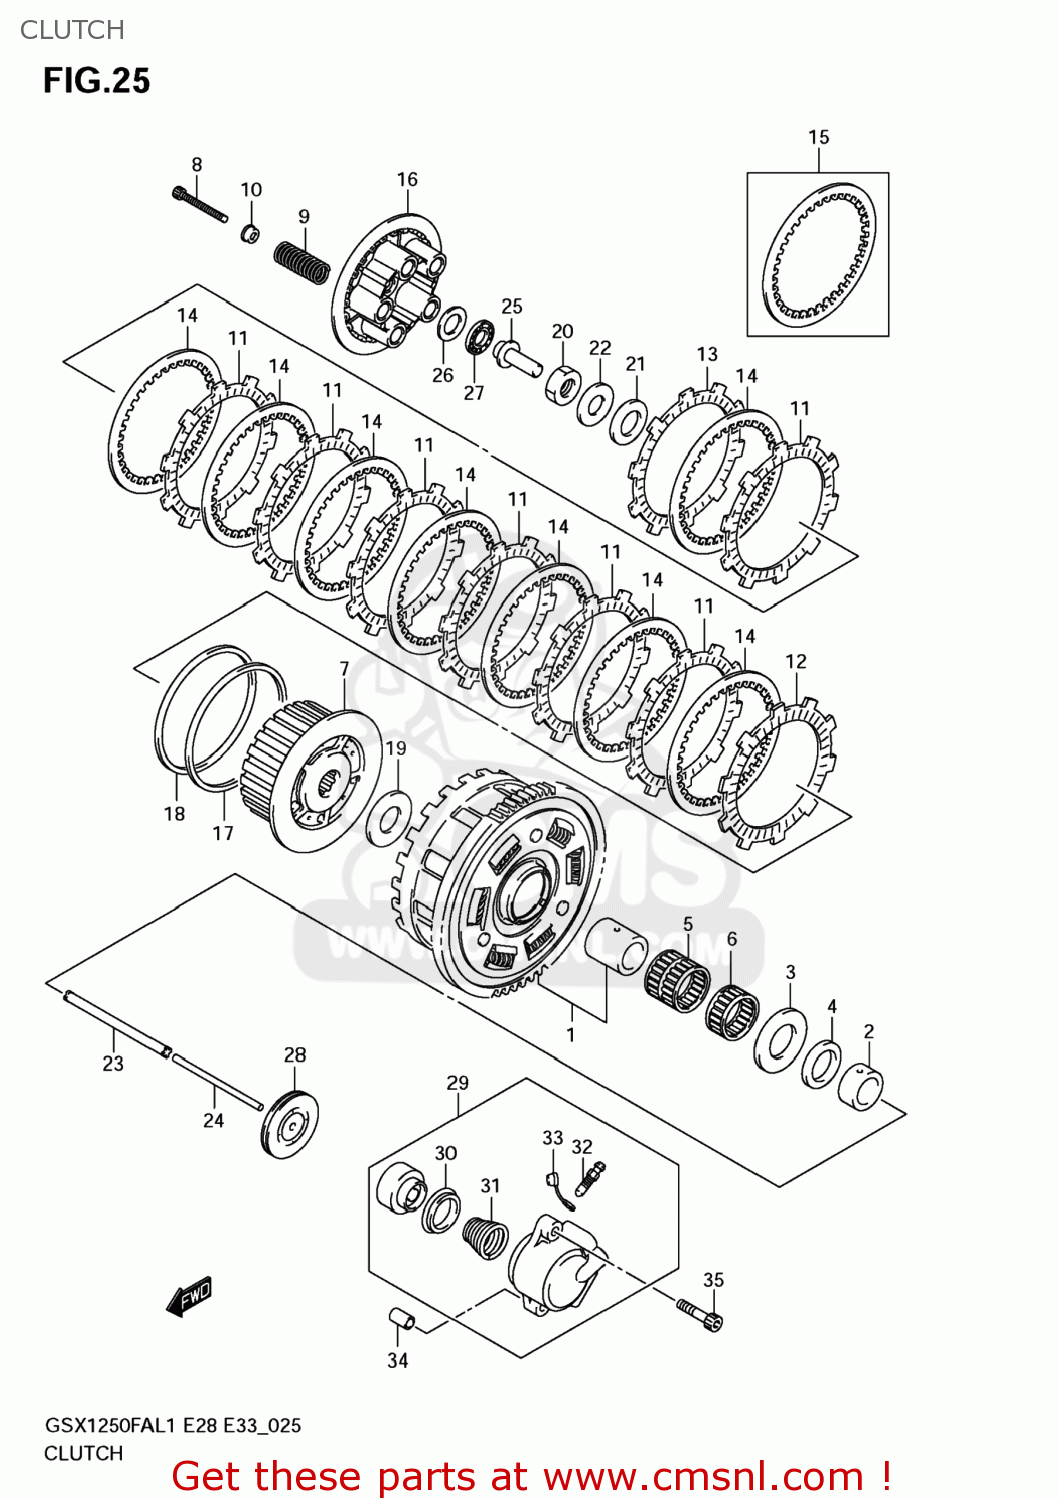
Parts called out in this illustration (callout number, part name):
1	GEAR ASSY,PRI DRIVEN(NT:83)
2	SPACER,OIL PUMP DRIVE SPROCKET
3	WASHER(25X54X2.4)
4	WASHER(25X30X3)
5	BEARING(35X40X26.8)
6	BEARING(35X40X12)
7	HUB,CLUTCH SLEEVE
8	BOLT,CLUTCH SPRING
9	SPRING,CLUTCH
10	WASHER
11	PLATE,CLUTCH DRIVE NO.1 (NAS)
12	PLATE,CLUTCH DRIVE NO.3 (NAS)
13	PLATE,CLUTCH DRIVE NO.2 (NAS)
14	PLATE,CLUTCH DRIVEN NO.1(T:2.0 (NAS)
15	PLATE,CLUTCH DRIVEN NO.2(T:2.3 (NAS)
16	DISC,CLUTCH PRESSURE
17	SEAT,WAVE WASHER
18	WASHER,CLUTCH PLATE WAVE
19	WASHER(25X50X2.5)
20	NUT
21	SHIM(25X38X1)
22	WASHER
23	ROD,CLUTCH PUSH,R(L:169)
24	ROD,CLUTCH PUSH,L(L:138)
25	PIECE,CLUTCH PUSH
26	WASHER(15.5X28X1)
27	BEARING(15X28X2)
28	SEAL,OIL(6X52X10)
29	CYLINDER,CLUTCH RELEASE
30	CUP,CLUTCH CYLINDER
31	SPRING,CLUTCH CYLINDER
32	BLEEDER
33	CAP,BLEEDER
34	PIN
35	BOLT(6X30)
